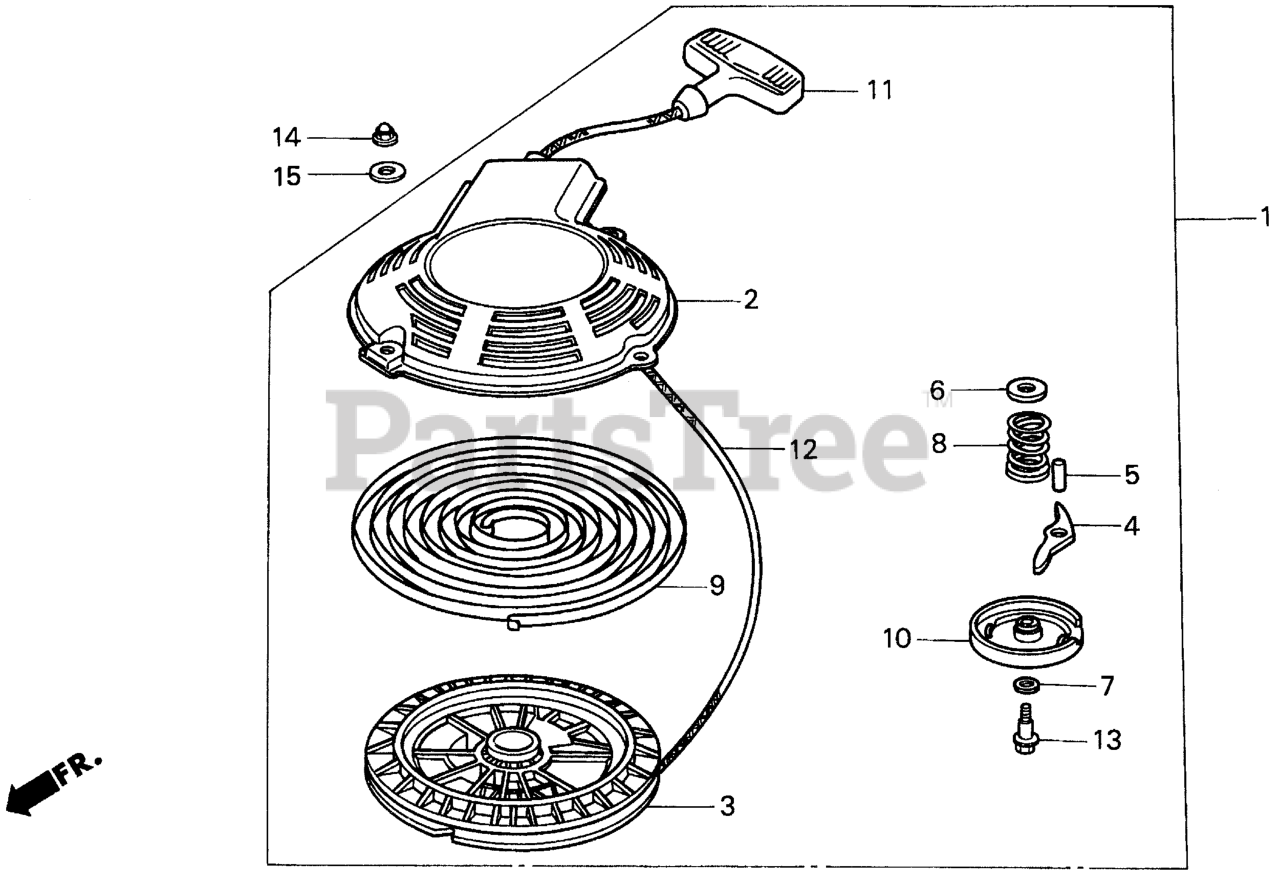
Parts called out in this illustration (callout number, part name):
1	STARTER ASSY., RECOIL
2	CASE, STARTER *R8* (BRIGHT RED)
3	REEL, STARTER
4	RATCHET, STARTER
5	SHAFT,RATCHET
6	PLATE A, FRICTION
7	PLATE B, FRICTION
8	SPRING, FRICTION
9	SPRING, RETURN
10	COVER, REEL STARTER
11	GRIP, STARTER
12	ROPE, STARTER (#3.5X100") (NA USE ALT:08535-ZG921-11)
13	BOLT, REEL COVER
14	NUT, FLANGE CAP (5MM)
15	WASHER, PLAIN (5MM)
